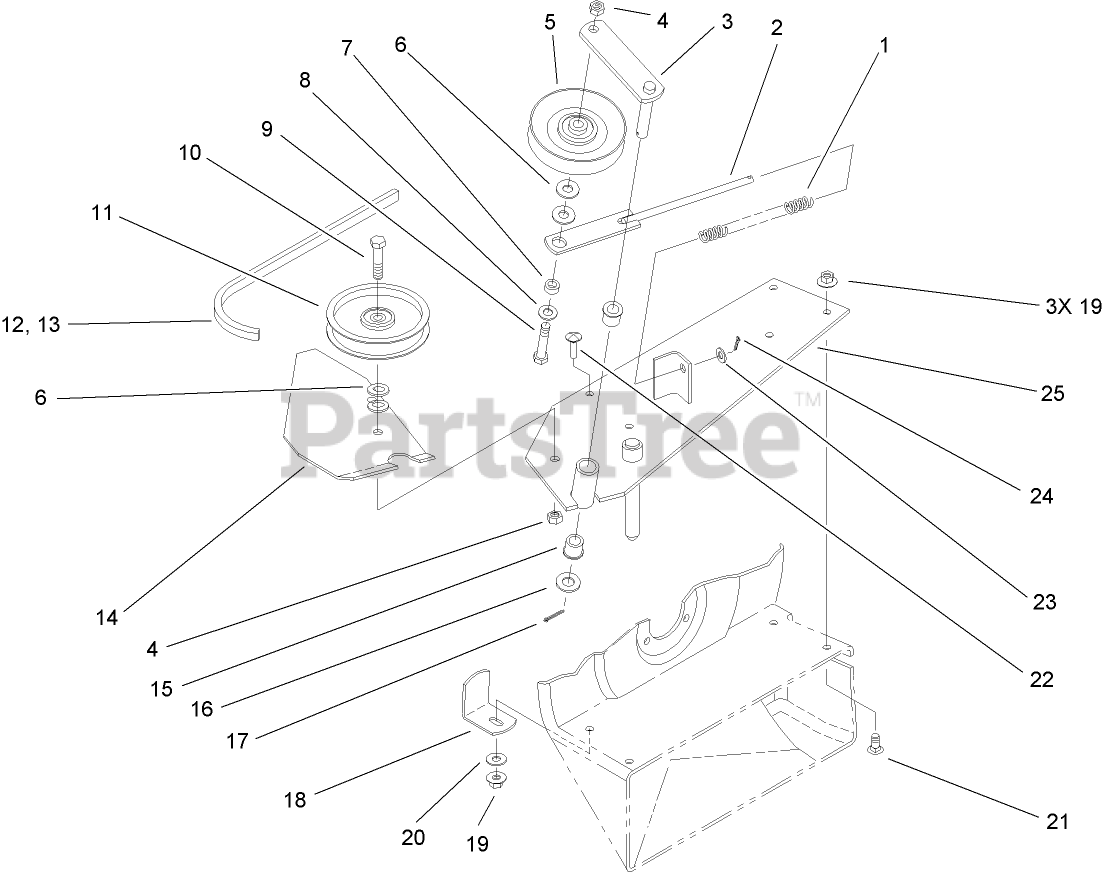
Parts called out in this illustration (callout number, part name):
1	SPRING-COMPRESSION
2	SPRING-ROD
3	IDLER ARM ASM
4	NUT-LOCK, NI
5	PULLEY-IDLER
6	WASHER-FLAT
7	SPACER
8	WASHER-FLAT
9	SCREW-HH
10	SCREW-HH
11	PULLEY-IDLER
12	V-BELT
13	V-BELT
14	SUPPORT-SHIELD, BELT
15	BUSHING
16	WASHER-FLAT
17	PIN-COTTER
18	BRACKET-SUPPORT, HOUSING
19	NUT-HF
20	WASHER-FLAT
21	BOLT-CARR
22	SCREW-CARR
23	WASHER-PLAIN
24	PIN-COTTER
25	BLOWER MOUNTING ASM
